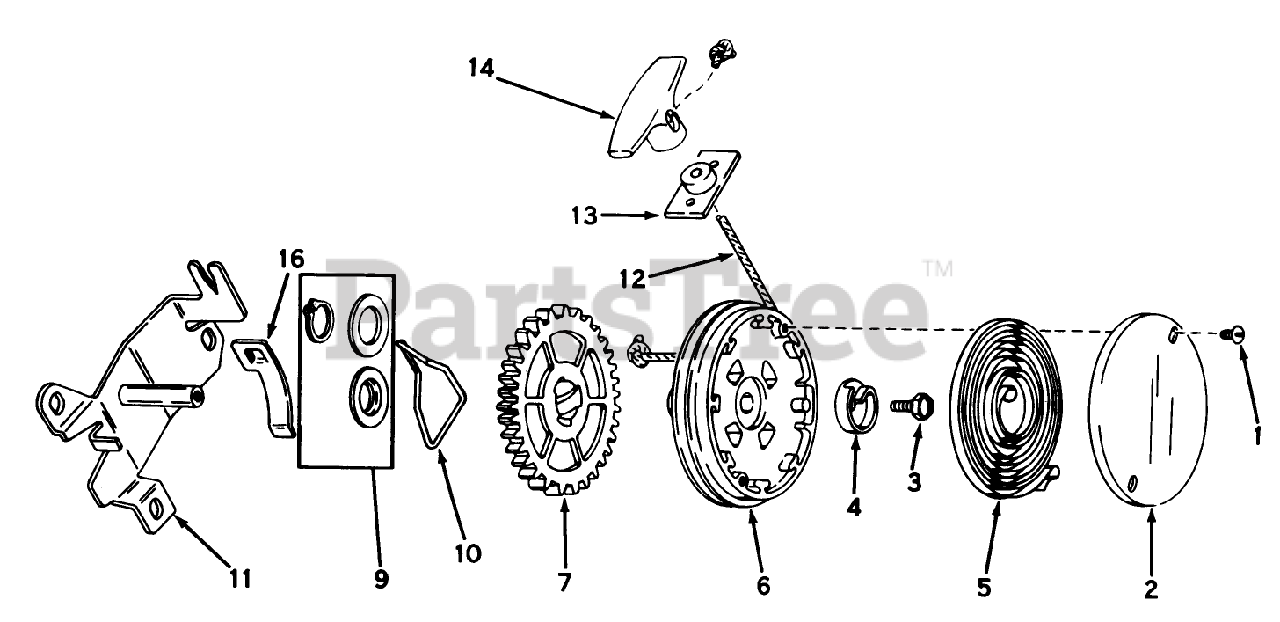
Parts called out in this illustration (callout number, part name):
1	Screw
2	Cover, Spring
3	Screw, Hex Washer Head
4	Hub Spring
5	Spring, Rewind
6	Pulley Assy. (Incl. No. 9)
9	Kit, Thrust Wash. Snap Rg.
10	Brake
11	Bracket Assy. Mounting
12	Rope-Starter
13	Bracket Assy.
14	Handle-Starter
16	Clip Rope
